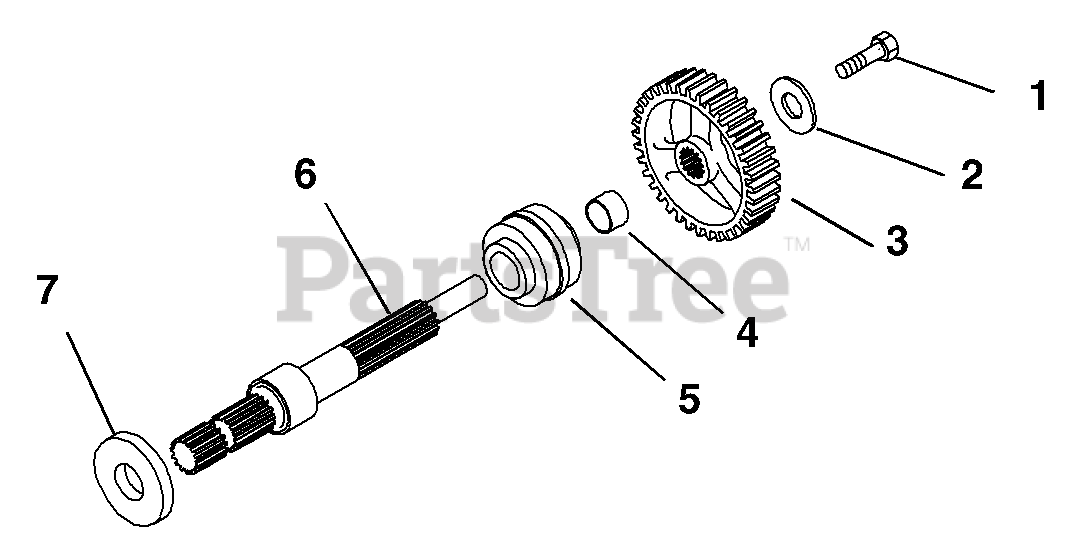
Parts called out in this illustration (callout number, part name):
1	Bolt-Hex .50-20 x 1.50
2	Washer-Flat-Steel .66 x 1.31 x .095
3	Gear, Spur PTO 10 Diametral Pitch 56 Teeth
4	Bushing-Sleeve Steel 1.06 x 1.38 x 1.38
5	Bearing-Assembly 1.00 x 1.98 x 1.24
6	Shaft, PTO
7	Seal 1.38 x 2.13 x .32
